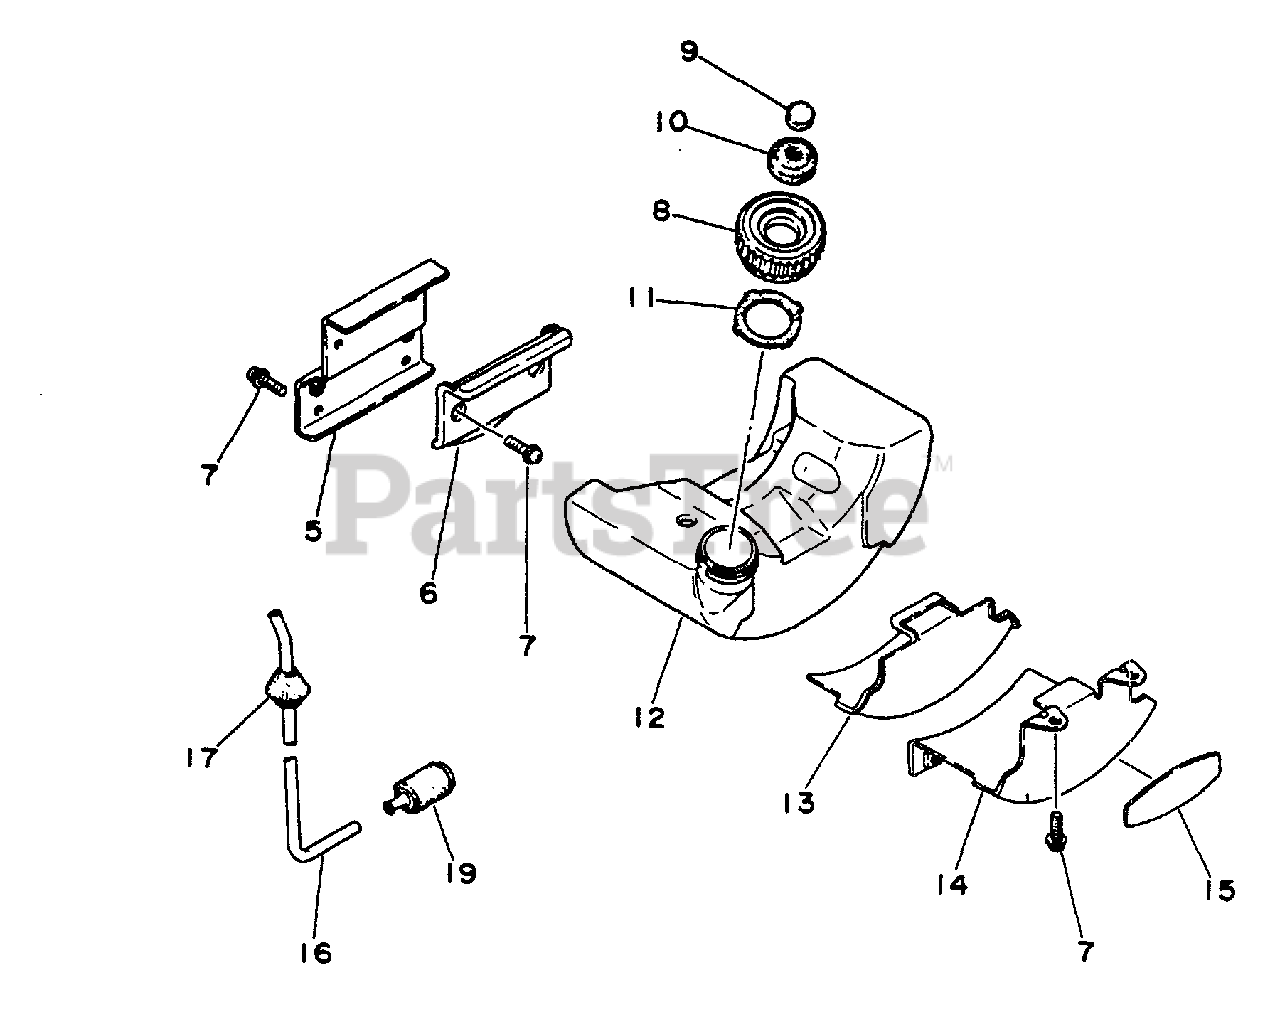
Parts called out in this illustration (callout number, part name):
5	BRACKET, FUEL TANK
6	CUSHION, FUEL TANK
7	SCREW 4×14
8	CAP ASSY
9	FILTER, CHECK VALVE
10	VENT ASSY
12	TANK, FUEL
14	BRACKET, FUEL TANK
15	LABEL - ECHO
16	PIPE, FUEL - 3×6×135
19	FILTER, FUEL
